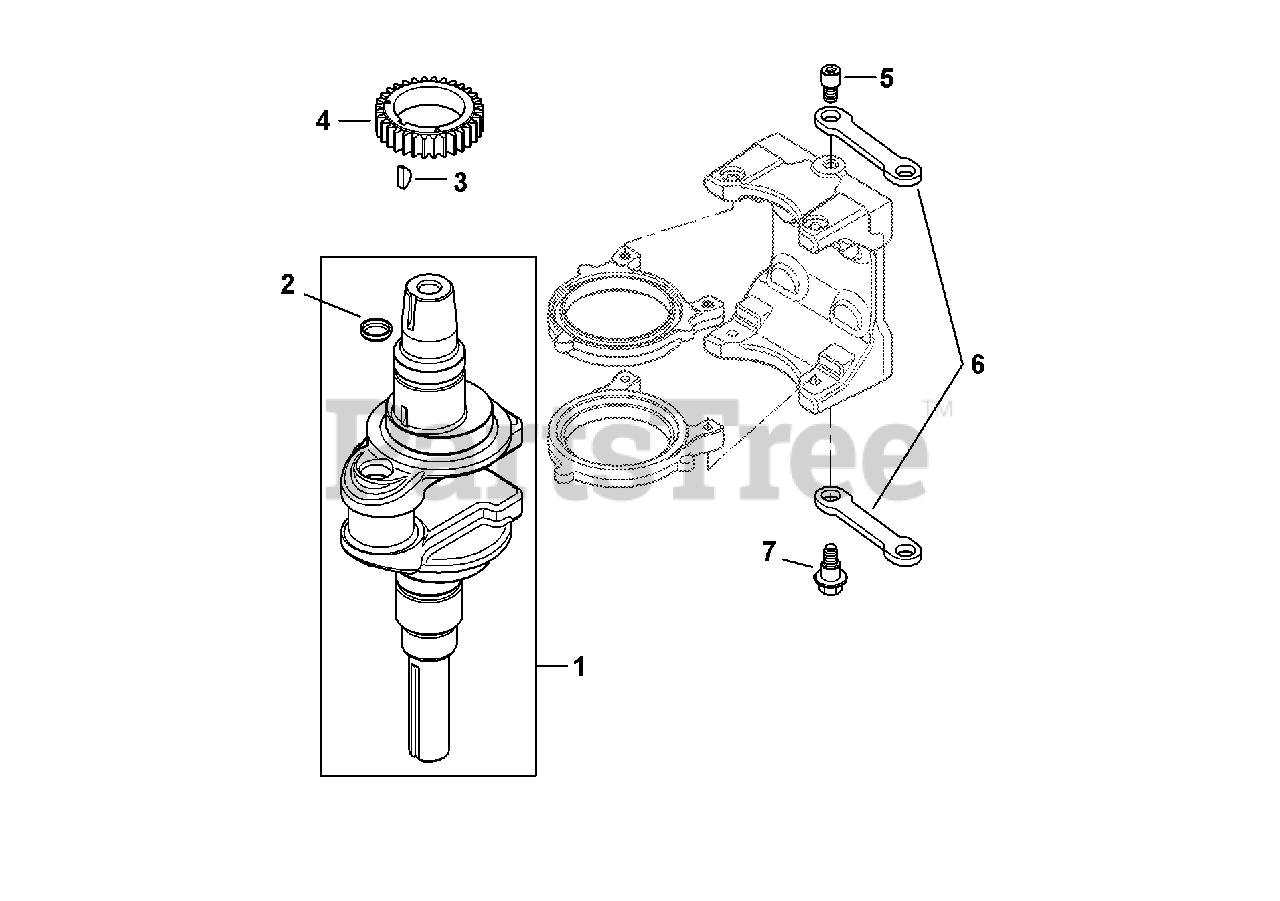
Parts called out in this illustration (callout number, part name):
1	Crankshaft Assembly Kit (Inc. 2)
3	Key, 3/16 X 5/8
4	Crankshaft Gear
5	Link Pivot Screw
6	Balance Weight Linkage
7	Shoulder Screw
